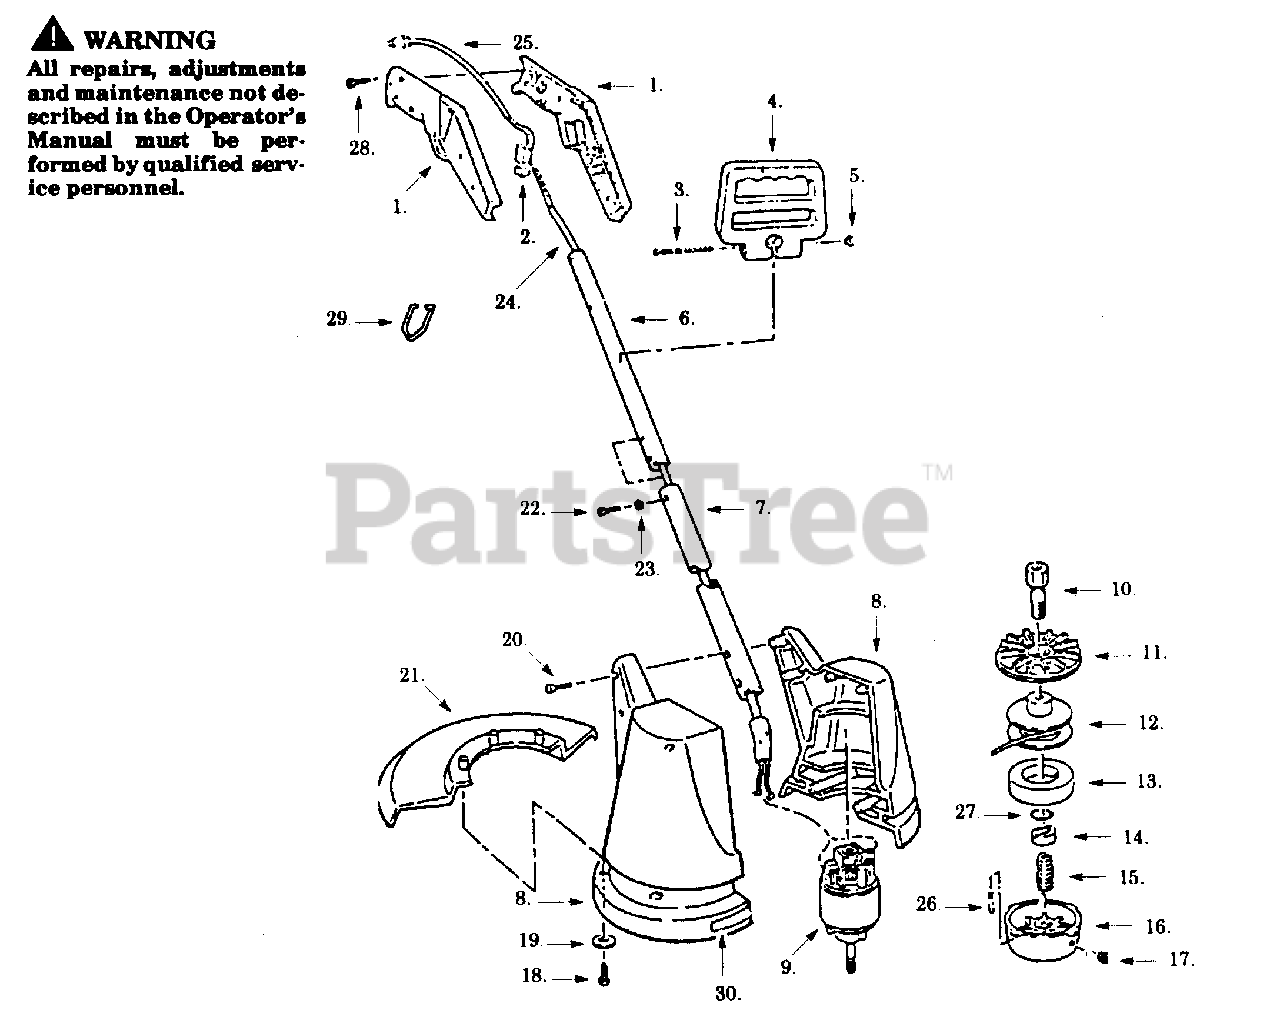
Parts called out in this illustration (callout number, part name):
1	R.H./L.H. Handle
2	Trigger Switch
4	Side Handle
5	Wing Nut
6	Upper Handle Tube
7	Lower Handle Tube
8	R.H./L.H. Housing
10	Drive Adapter
11	Rear Plate
12	Spool & Line
13	Foam Pad
14	Drive Adapter Nut
21	Line Cutter Guard
23	Lockwasher
25	Power Cord
26	Cotter Pin
30	15" Cut Label (Not a serviceable part)
